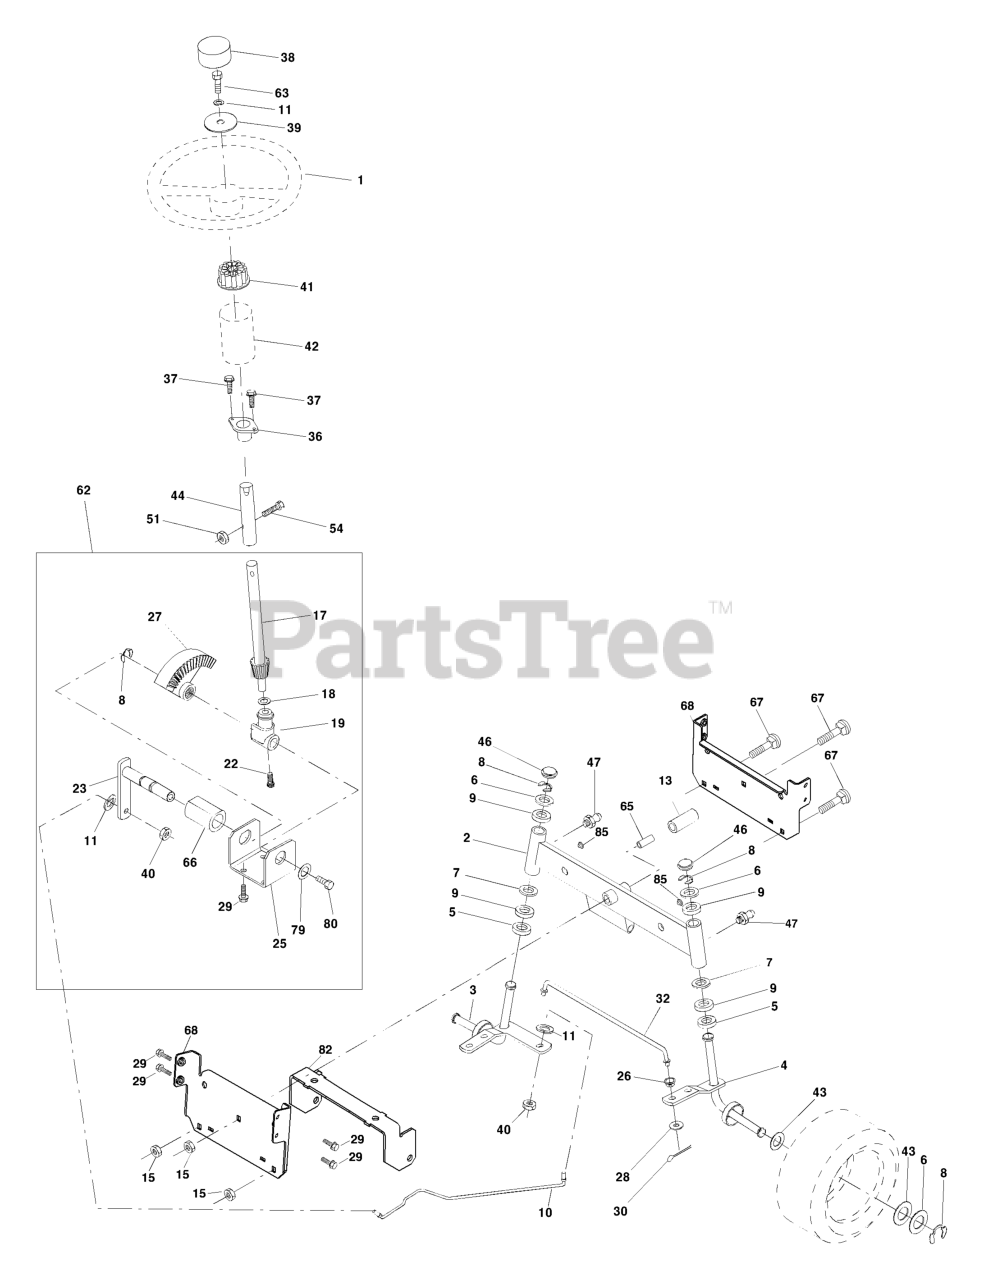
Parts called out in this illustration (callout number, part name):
1	STEERING WHEEL
2	AXLE ASSY
3	SPINDLE.ASM.LH.15"TIRES
4	SPINDLE.ASM.RH.15"TIRES
5	THRUST WASHER
9	BRNG T
10	DRAGLINK.15".TIRES
11	WASHER, LOCK 3/8
13	TUBE, PIVOT AXLE
15	NUT
17	SHAFT ASM STEERING
18	THRUST WASHER
19	STEERING SHAFT SUPPORT
22	SCREW.HX.WSH.HD
23	SHAFT ASSY PITTMAN
25	BRACKET STEERING
26	BUSHING.DRAGLINK (2 2)
27	GEAR.SECTOR
28	WASHER
29	SCREW 3/8-16X3/4
30	COTTER PIN
32	TIE ROD
36	BUSHING, STEERING
37	SCREW.TT.#10-32X.5.3/8.FLANGE
38	CAP.WHEEL.STEERING.GREY
39	Washer 13/32 X 1-1/20 x 11 Ga
40	GRIPCO NUT
41	STEERING WHEEL ADAPTOR
42	BOOT STEERING
44	EXT SHAFT STEERING
46	CAP.SPINDLE.BLACK
47	ZERK M
51	NUT.71038.31-18.HEX.NYLOCK
54	BOLT.5/16-18X1-1/4 FULL.THREAD
62	STEERING KIT
63	BOLT
65	SPACER BRACE AXLE
66	BEARING ARM
67	BOLT
68	BRACE.AXLE.15"TIRES
79	WASHER
80	BOLT.HX.NYLON3/8-16X
82	BRACKET
85	FASTENER.XMAS.TREE
